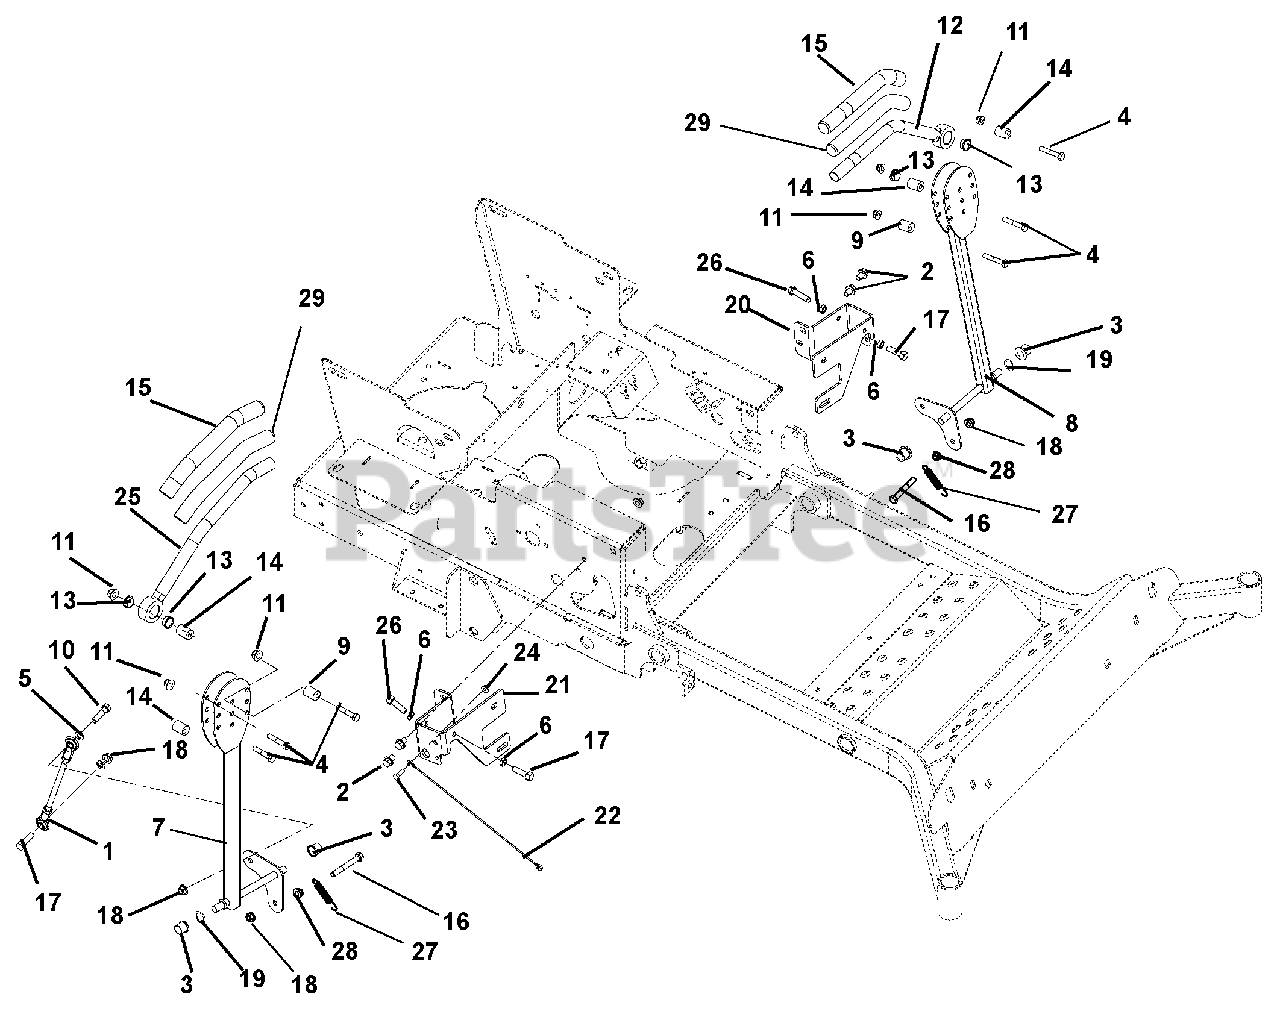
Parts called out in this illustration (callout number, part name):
1	ASM, STEERING LINKAGE
2	@SCR-TAP .38-16X.50 HWH TR YWZ
3	BSHG-FLG .515X.750X.745X1.00NY
4	@BLT-HEX .31-18X1.75 GR5 YWZC
5	@WSHR-LK .38X.094 REG YWZC
6	NUT-HEX-JAM .375-16 YWZC
7	WMT, RH CONTROL
8	WMT, LH CONTROL
9	BSHG, ECCENTRIC .328X.750X.970
10	@BLT-HEX .38-16X1.50 GR5 YWZC
11	@NUT-LK-NYL-FLG .31-18 YWZC
12	HANDLE WLDMT LH
13	BSHG-FLG .762X1.48X.44 NYL
14	SPACER .328 X .76 X 1.01
15	GRIP, HANDLEBAR
16	@BLT-HEX .38-16X2.75 GR5 YWZC
17	@BLT-HEX .38-16X1.25 GR5 YWZC
18	@NUT-LK-NYL-FLG .38-16 YWZC
19	WAVE WASHER .640X.875X.125FH
20	LH STEERING STOP BRACKET - RED
21	RH STEERING STOP BRACKET - RED
22	CABLE, 12.0 LANYARD, NYLON
23	@BLT-HEX .25-20X.75 GR5 YWZC
24	@NUT-LK-NYL-FLG .25-20 YWZC
25	WLDMT, RH HANDLE
26	@BLT-HEX .38-16X.75 GR5 YWZC
27	SPRING,EXT,.061X.50X3.0
28	@NUT-SPNLK-FLG .375-16 YWZC
29	TUBE, .88ID X 1.00OD X 10.25
